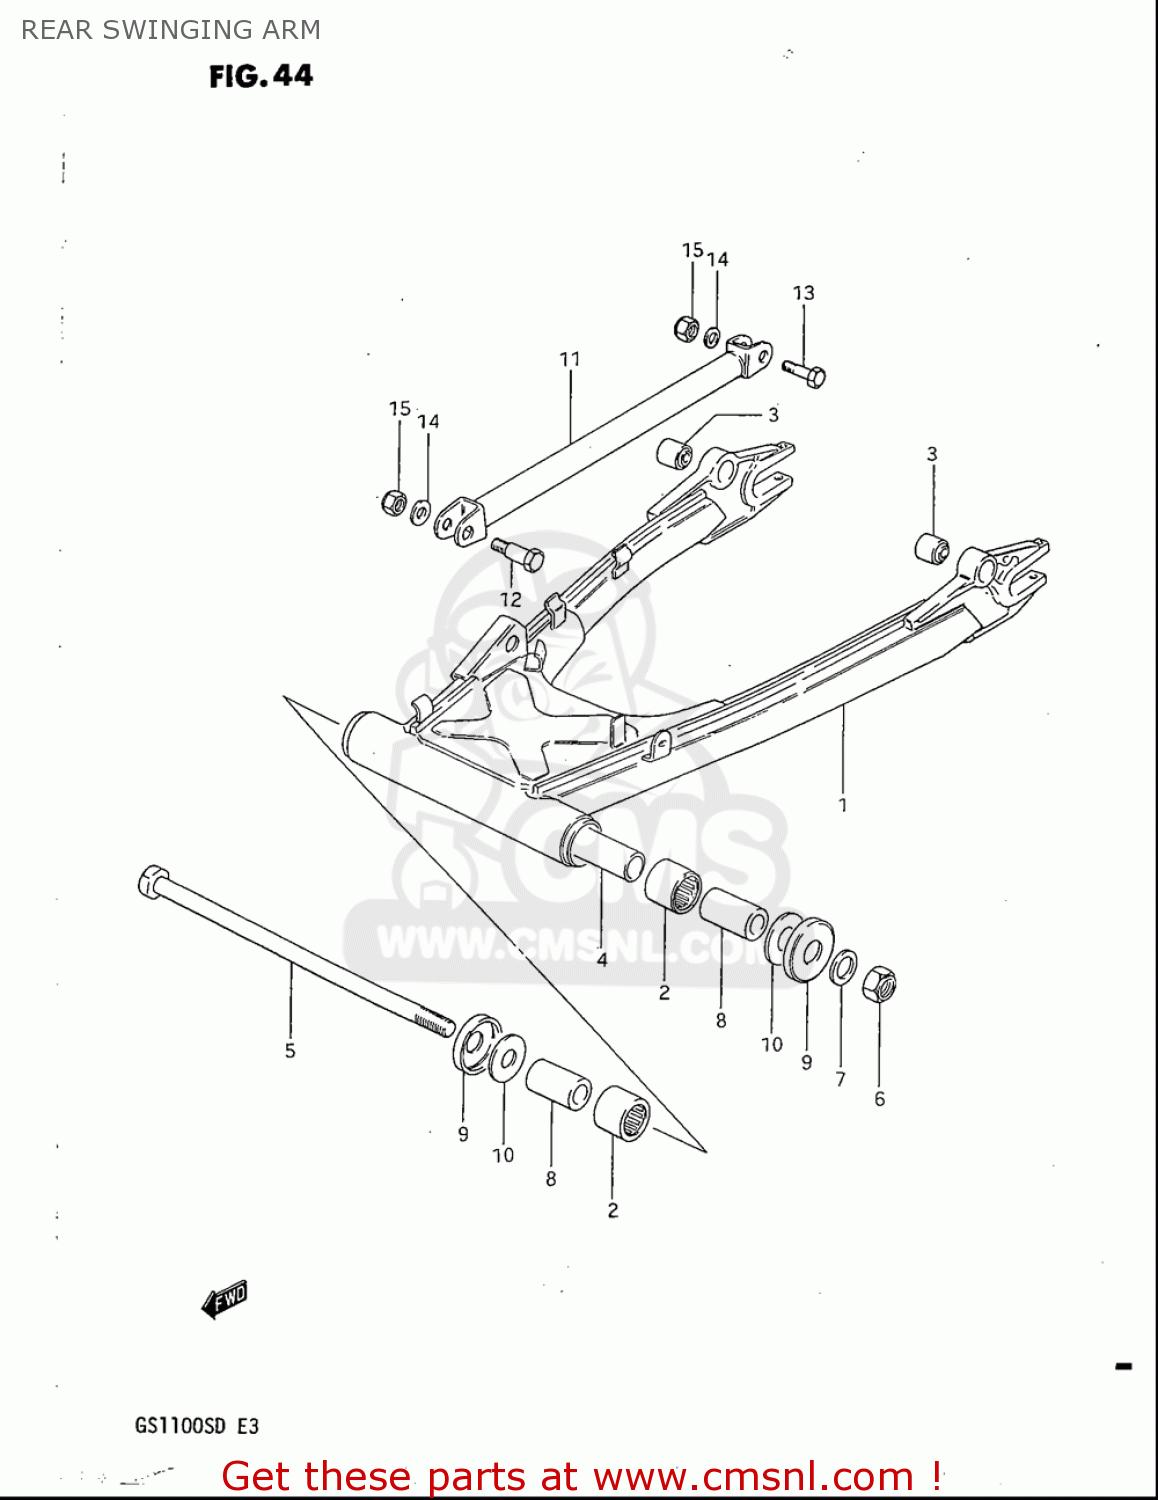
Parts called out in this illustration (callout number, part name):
2	BEARING(25X33X30)
3	BUSH
4	SPACER,RR SWGARM PIVOT CTR
5	SHAFT,RR SWINGINGARM PIVOT
6	NUT 16MM
7	WASHER
8	SPACER,RR SWGARM PIVOT
9	COVER,RR SWINGINGARM PIVOT
10	WASHER
11	LINK,RR TORQUE
12	BOLT M10X39
13	BOLT(10X39)
14	WASHER
15	NUT
